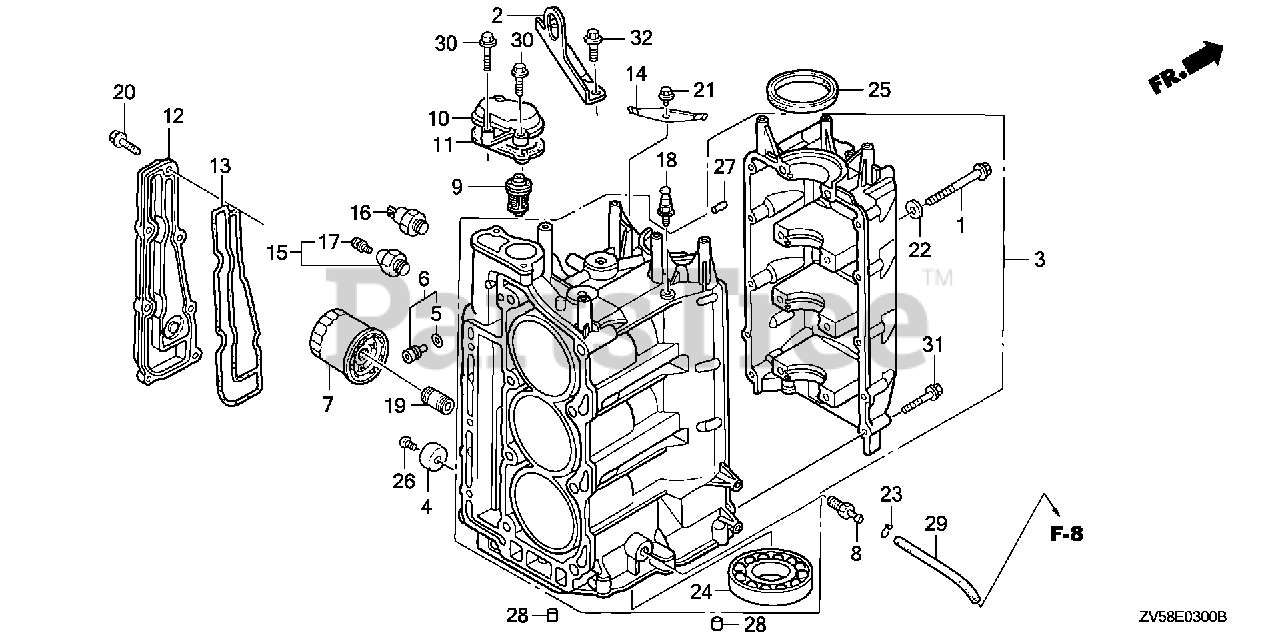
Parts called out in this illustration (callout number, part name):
1	BOLT, FLANGE (8X94)
2	HANGER, ENGINE
3	BLOCK ASSY., CYLINDER *NH8* (DARK GRAY) (NOT AVAILABLE)
4	METAL, ANODE
5	O-RING (4.8X1.9)
6	ORIFICE ASSY., OIL PASSAGE
7	FILTER, OIL
7	FILTER, OIL (TOYO ROKI)
7	FILTER, OIL (DENSO)
8	JOINT, WATER HOSE
9	THERMOSTAT ASSY. (72 DEGREES C)
10	COVER, THERMOSTAT
11	GASKET, THERMOSTAT COVER
12	COVER, WATER JACKET
13	GASKET, WATER JACKET COVER
14	HOLDER, WIRE (A)
15	SWITCH, OIL PRESSURE
16	SWITCH ASSY., THERMOSTAT
17	SCREW-WASHER (4X8)
18	BOLT, TIMING BELT ADJUSTING SPRING
19	HOLDER, OIL FILTER
20	BOLT, FLANGE (6X22)
20	BOLT, FLANGE (6X22) (CT200)
21	BOLT, FLANGE (6X12)
22	WASHER, PLAIN (8MM)
23	CLIP, TUBE (B8)
24	BEARING, RADIAL BALL (6005)
25	OIL SEAL (56X70X8)
26	SCREW, PAN (6X18)
27	PIN, DOWEL (10X12)
28	PIN A, DOWEL (12X16)
28	PIN, DOWEL (6X10)
29	BULK HOSE, VACUUM (4.5X1000) (4.5X290)
30	BOLT, FLANGE (6X20)
31	BOLT, FLANGE (6X40)
32	BOLT, FLANGE (8X18)
